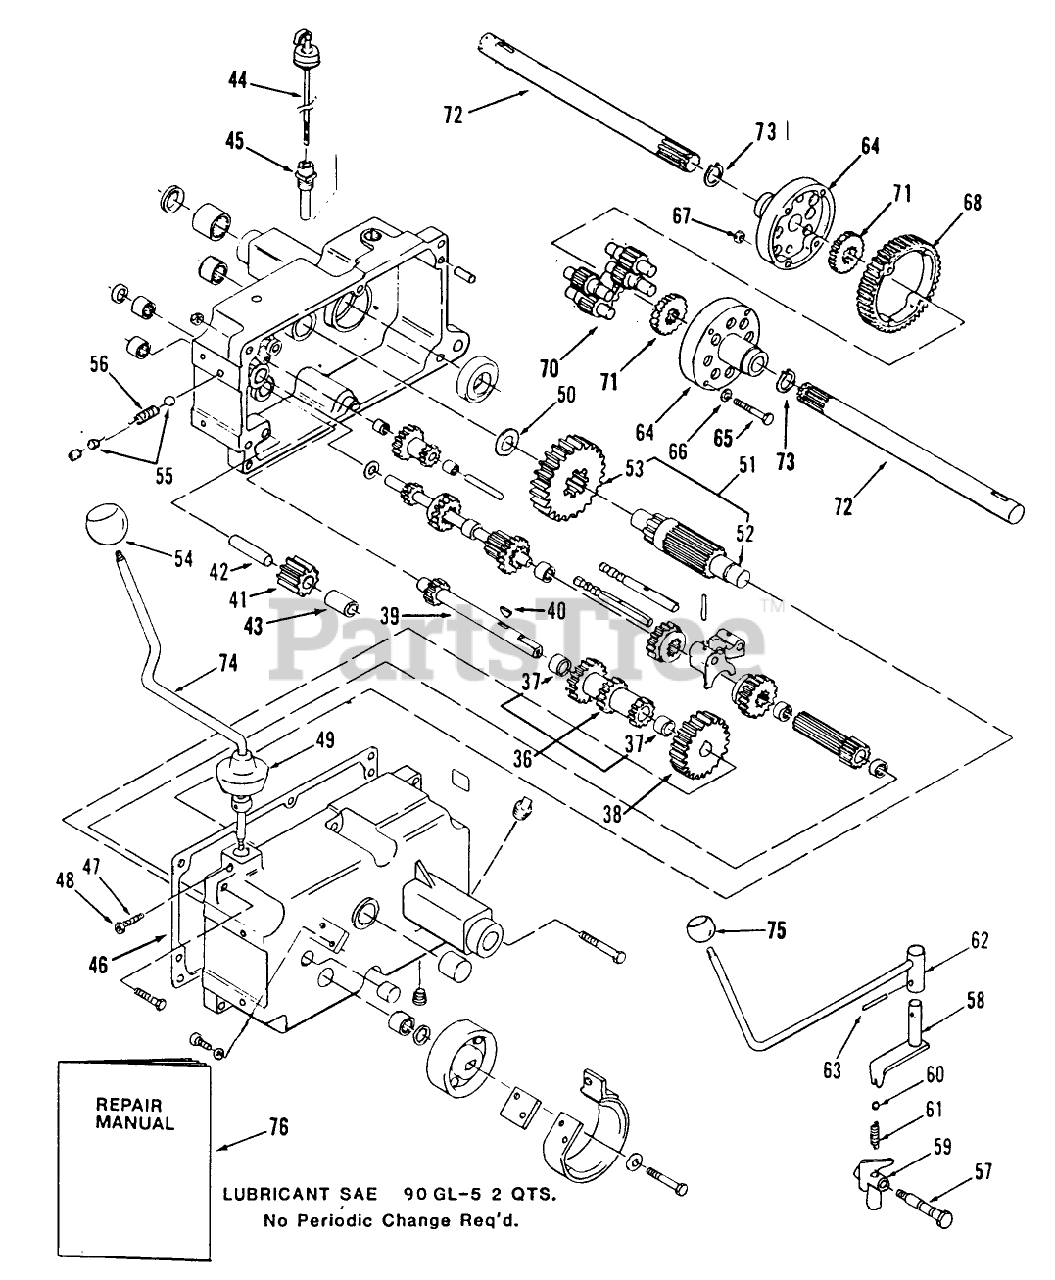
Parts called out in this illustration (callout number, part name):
36	GEAR-CLUSTER
37	BUSHING-BRONZE
38	GEAR-CLUSTER SHAFT
40	KEY-WOODRUFF
41	GEAR/BUSHING ASM-REVERSE IDLER
42	PIN-DIFFERENTIAL
43	BUSHING
45	NIPPLE-TRANS FILL
46	GASKET-TRANSMISSION
47	SETSCREW
49	COVER-DUST
50	WASHER-THRUST
51	GEAR ASM
52	PINION SHAFT
55	BALL-DETENT
56	SPRING-SHIFT STOP
57	BOLT-DETENT
58	SHIFT ASM
60	BALL-DETENT
61	SPRING-SHIFT STOP
62	SHIFT ROD ASM
63	PIN-SPIROL
66	WASHER
67	NUT-HEX
70	GEAR-PINION, 11T
71	AXLE GEAR
76	MANUAL
